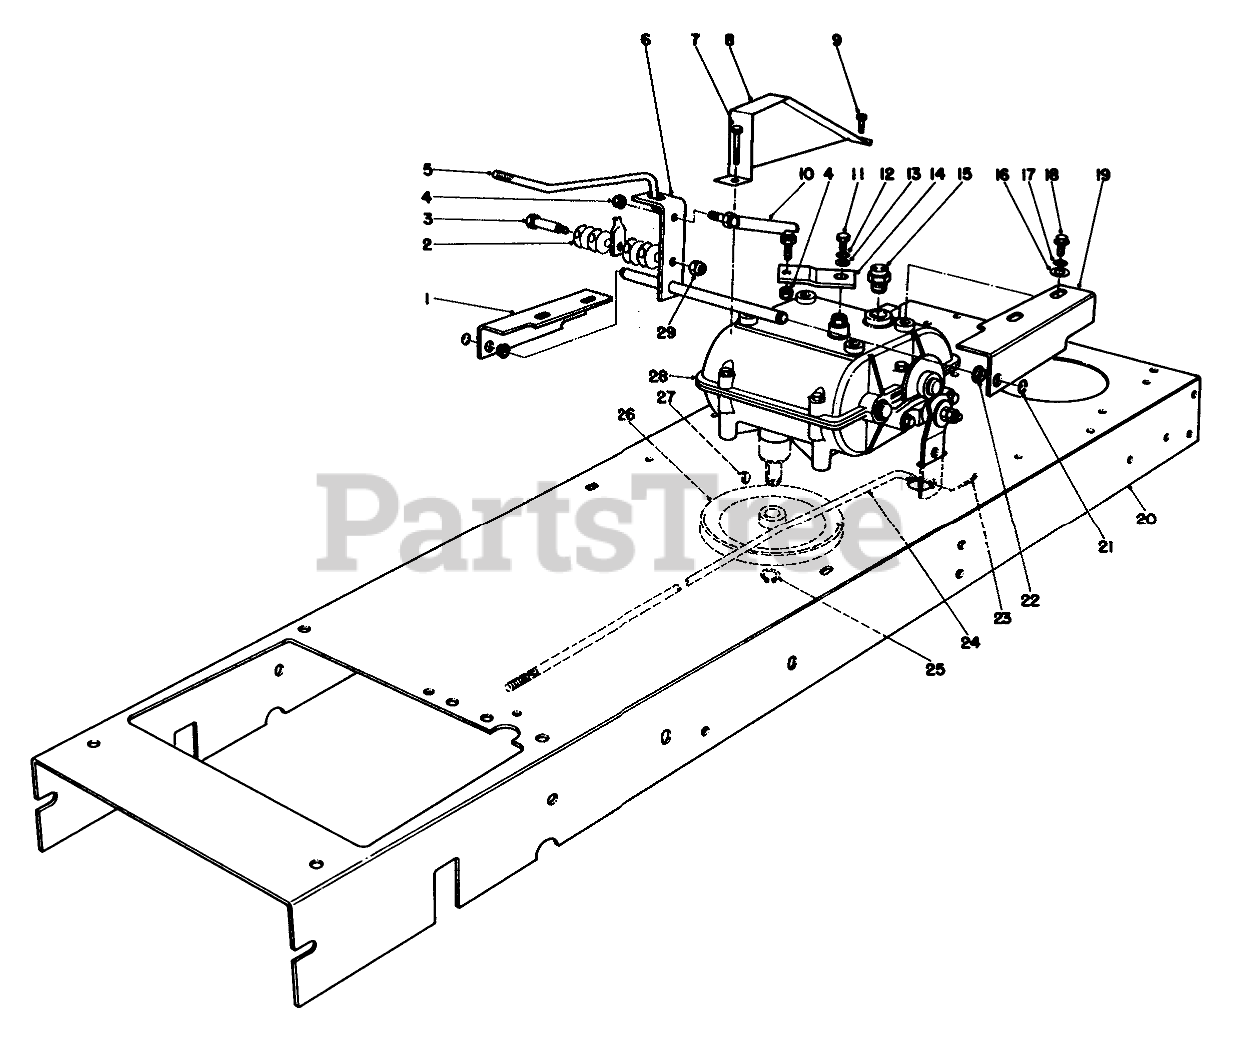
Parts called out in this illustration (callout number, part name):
1	Bracket-Shift R.H.
2	WASHER-BELLEVILLE
3	BOLT-SHOULDER
4	NUT-LOCK, NI
5	Lever-Shift
6	SHIFT LEVER WA B
7	SCREW-HH
8	CHAIN GUARD R
9	SCREW-HH
10	TIE ROD SHIFT
11	SCREW-HH
12	WASHER-LOCK
13	WASHER-FLAT
14	SHIFT LEVER LINK BO
15	NEUTRAL SWITCH
16	WASHER-PLAIN
17	WASHER-LOCK
18	SCREW-HWHTF
19	51-1710T BRKT B
20	Frame-Main
21	E-RING EXTERNAL
22	NYLINER #7L2FF TYPE 7
23	PIN-COTTER
24	Rod-Brake
25	RING-SNAP, EXTERNAL
26	PULLEY
27	KEY-WOODRUFF
28	TRANSMISSION
29	NUT-LOCK, NI
